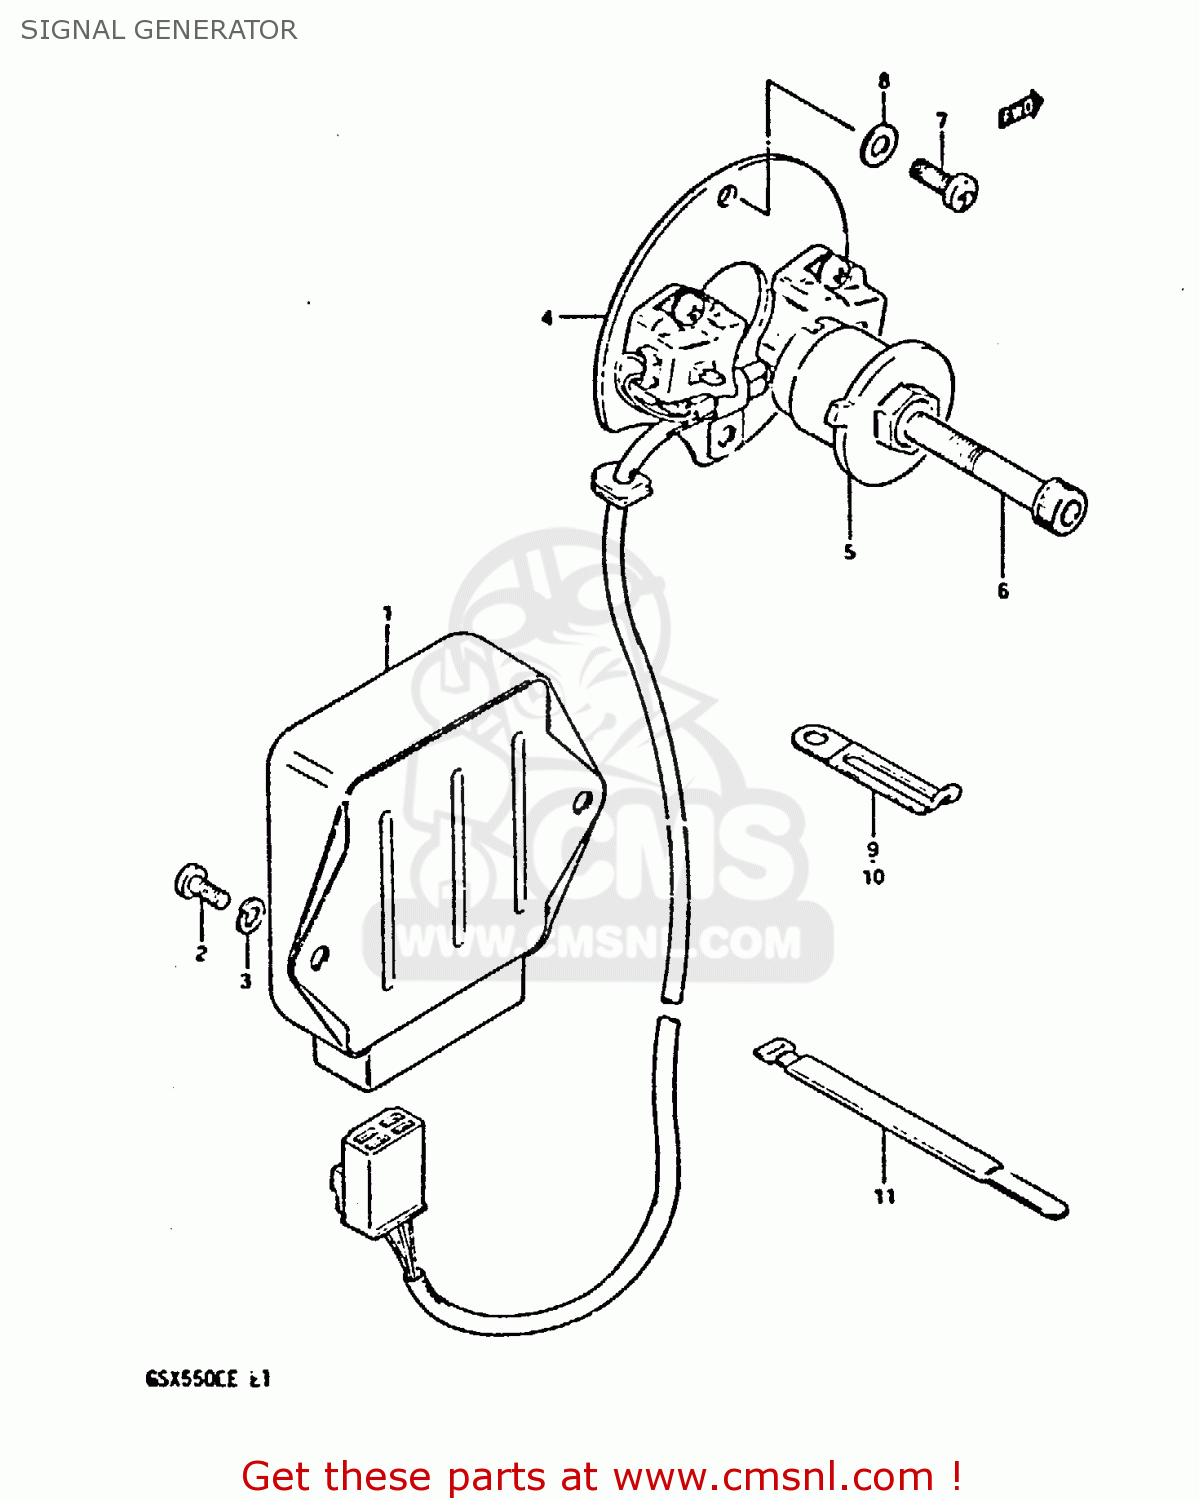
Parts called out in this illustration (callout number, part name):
1	IGNITER UNIT ASSEMBLY
2	SCREW 6X12
3	LOCK WASHER
4	GENERATOR ASSY,SIGNAL
5	ROTOR,SIGNAL
6	BOLT
7	SCREW(5X12)
8	WASHER
9	CLAMP L:35
10	CLAMP
11	CLAMP
